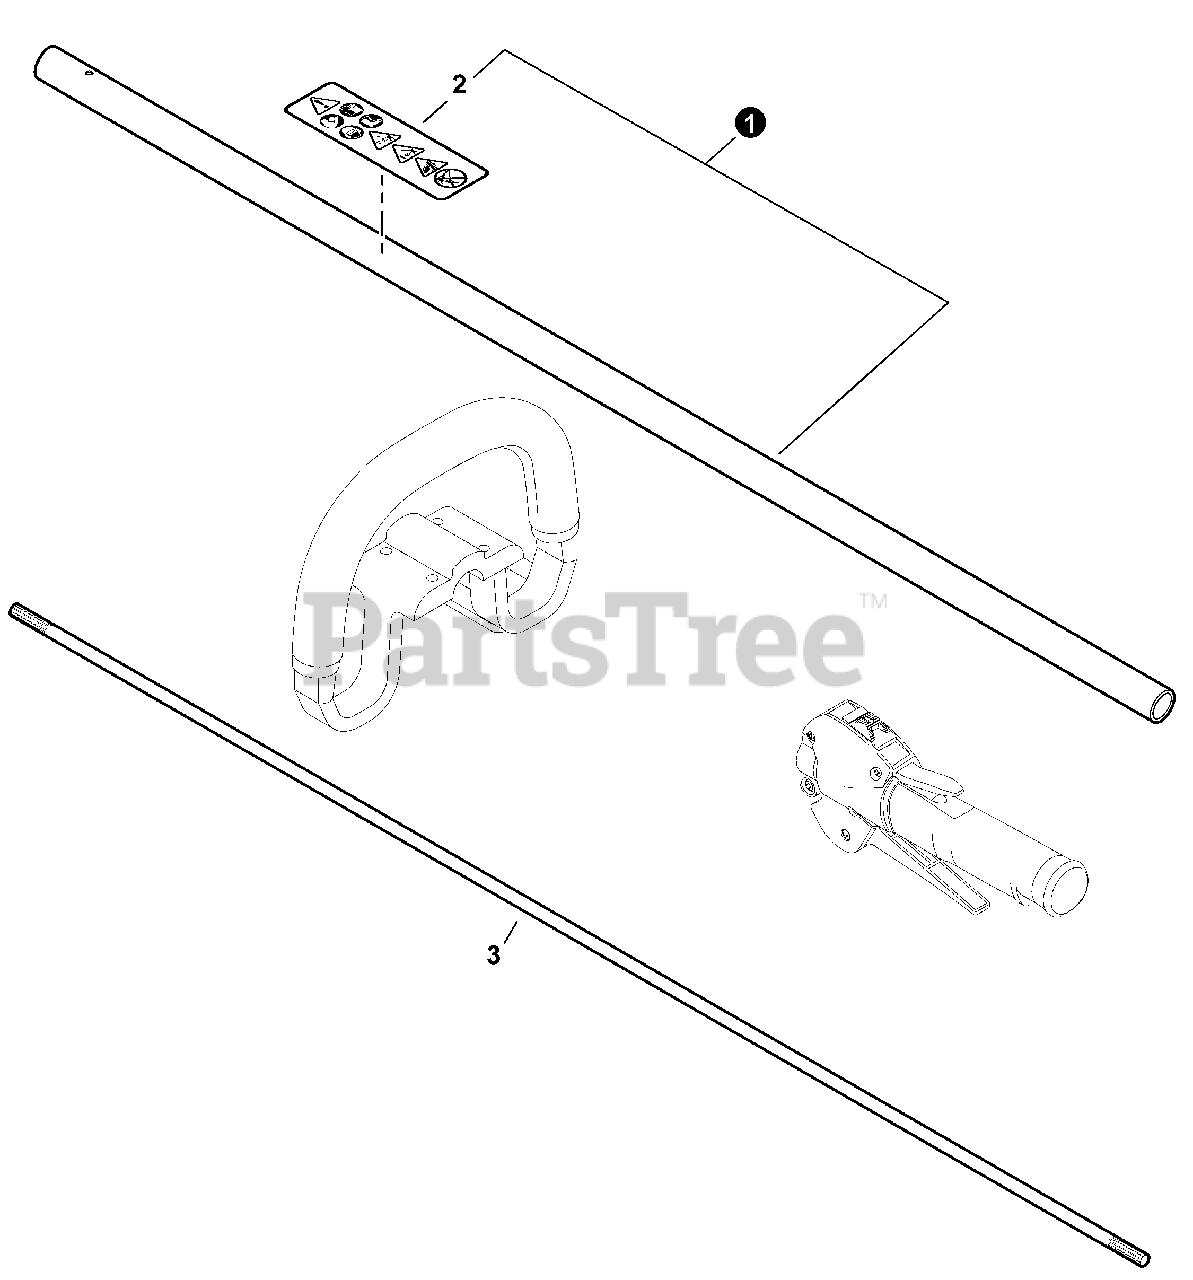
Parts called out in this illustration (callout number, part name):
1	MAIN PIPE ASSY
2	LABEL - CAUTION
3	MAINSHAFT
